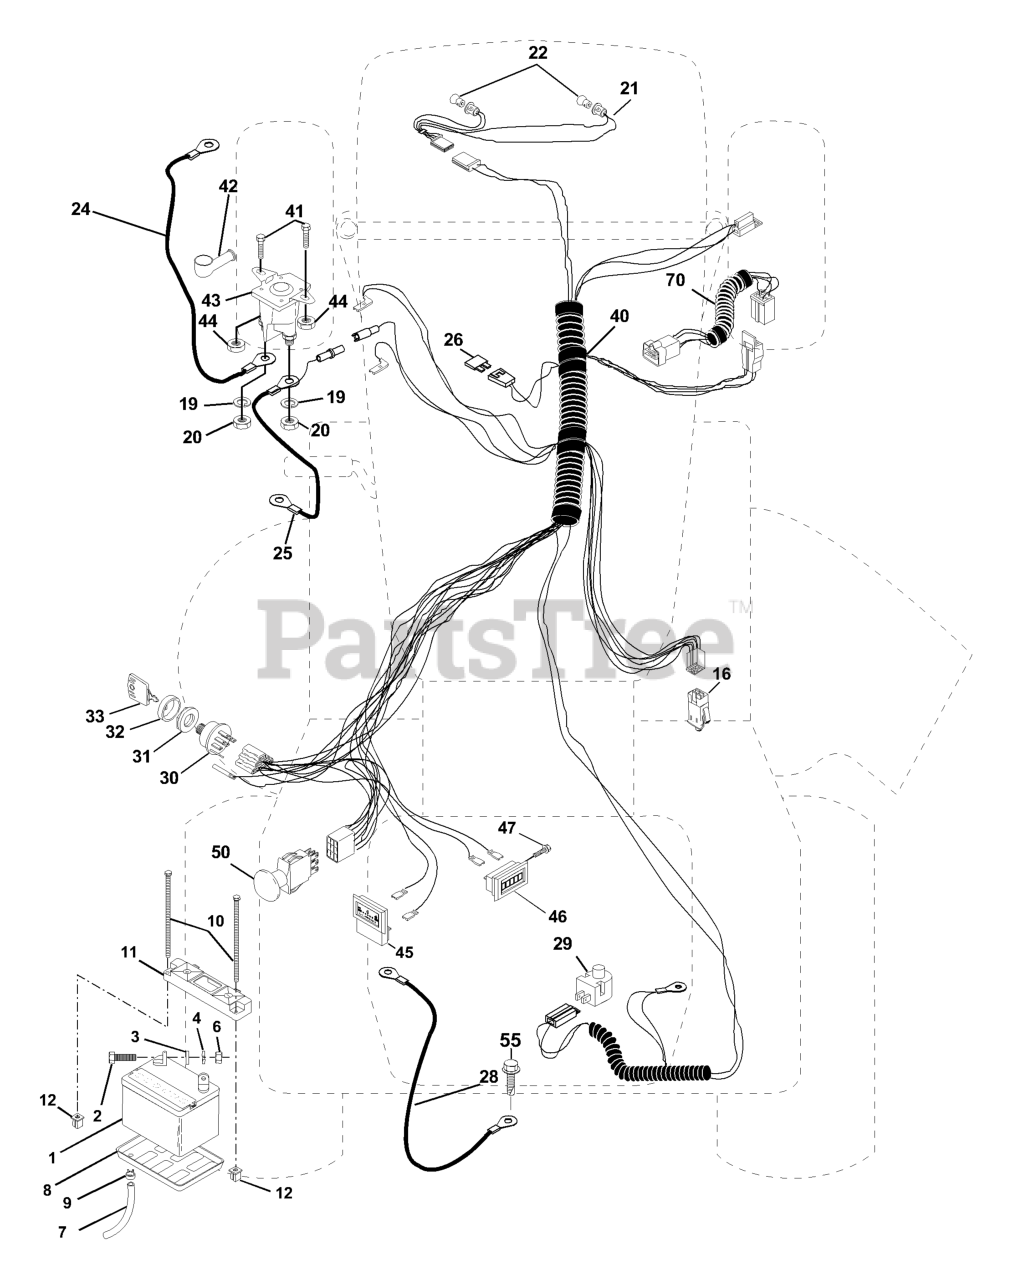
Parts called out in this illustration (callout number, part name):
1	BATTERY
2	BOLT.HEX.1/4.X.3/4.DICHROMATE
3	WASHER
4	LOCKWASHER
6	NUT
7	PLASTIC TUBE
8	BATTERY TRAY T
9	HOSE CLAMP T
10	BOLT 1/4-20 X 7.5
11	BATTERY HOLDDOWN FRONT MOUNT
12	NUT, PUSH NYLON 1/4" BATTERY
16	SWITCH INTERLOCK
19	LOCKWASHER
20	NUT
21	HARNESS LIGHT SOCKET
24	BATTERY CABLE GT
25	CABLE BATTERY 6 GA 22" W/16W
28	CABLE GROUND 6 GA 21" 90T BLK
29	RP.SWITCH.PLUNGER.NC.GRAY
30	SWITCH.IGNITION.4.POSITION
31	NUT IGNITION
32	COVER SWITCH KEY
33	KEY.MOLDED.GENERIC
40	IGN HARNESS
41	BOLT
42	TERMINAL COVER
43	SOLINOID
44	Nut Keps Hex 1/4-20 Unc
46	HOUR METER T
47	Screw 10-24 x 1/2 Black
50	SWITCH PTO 3 PDT
55	Screw Thdrol 5/16-18 x 1/2 TYT
70	WIRING HARNESS
